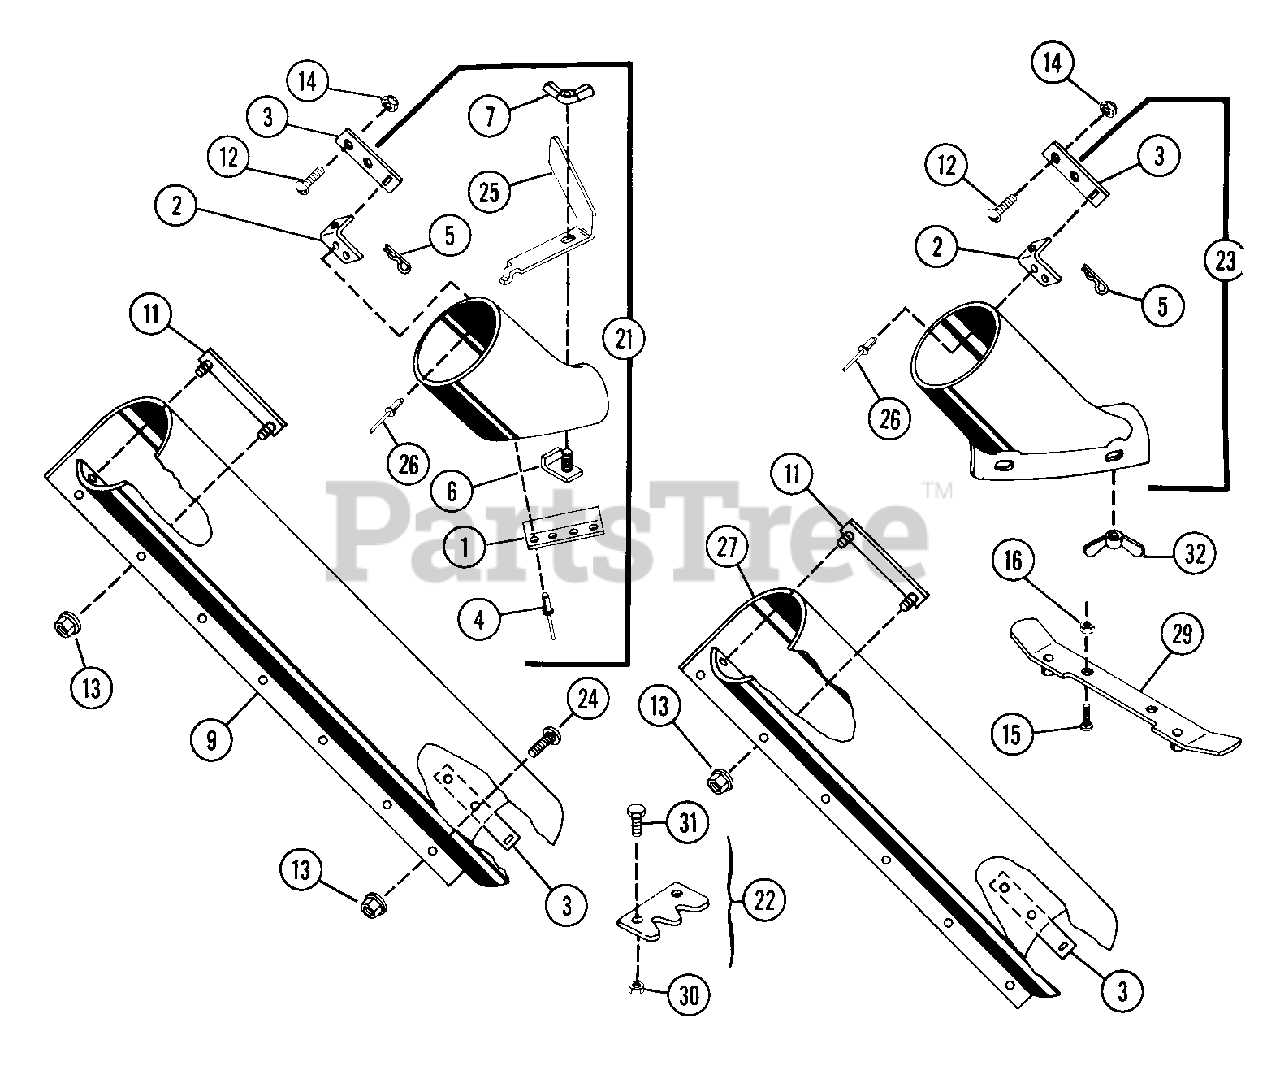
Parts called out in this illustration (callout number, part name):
2	RETAINER
3	STRAP
5	PIN-HAIR INT .09X.188 PL
10	SCR-TAP .312-18X.50 HWH PL TR
12	SCR-MCH 10-24X.38 SLTOR PAN PL
13	NUT-LK-FLG .250-20 PL
14	NUT-LK TOP 10-24 PL
15	BLT-RDHDSQNK .25-20X1.00 GR5
16	NUT-LK-CTR .250-20 PL
22	SERVICE VANE PACKAGE
23	BOOT ASSEMBLY 32 IN
26	RVT-TBLR .187X.375 OH ST PL
27	28 IN & 32 IN TUBE BLANK
29	LATCH SPRING
30	NUT-LK TOP .312-24 PL GR C
31	BLT-HEX .31-24X.75 GR8
32	NUT-WING W/INSERT .312 - 18
